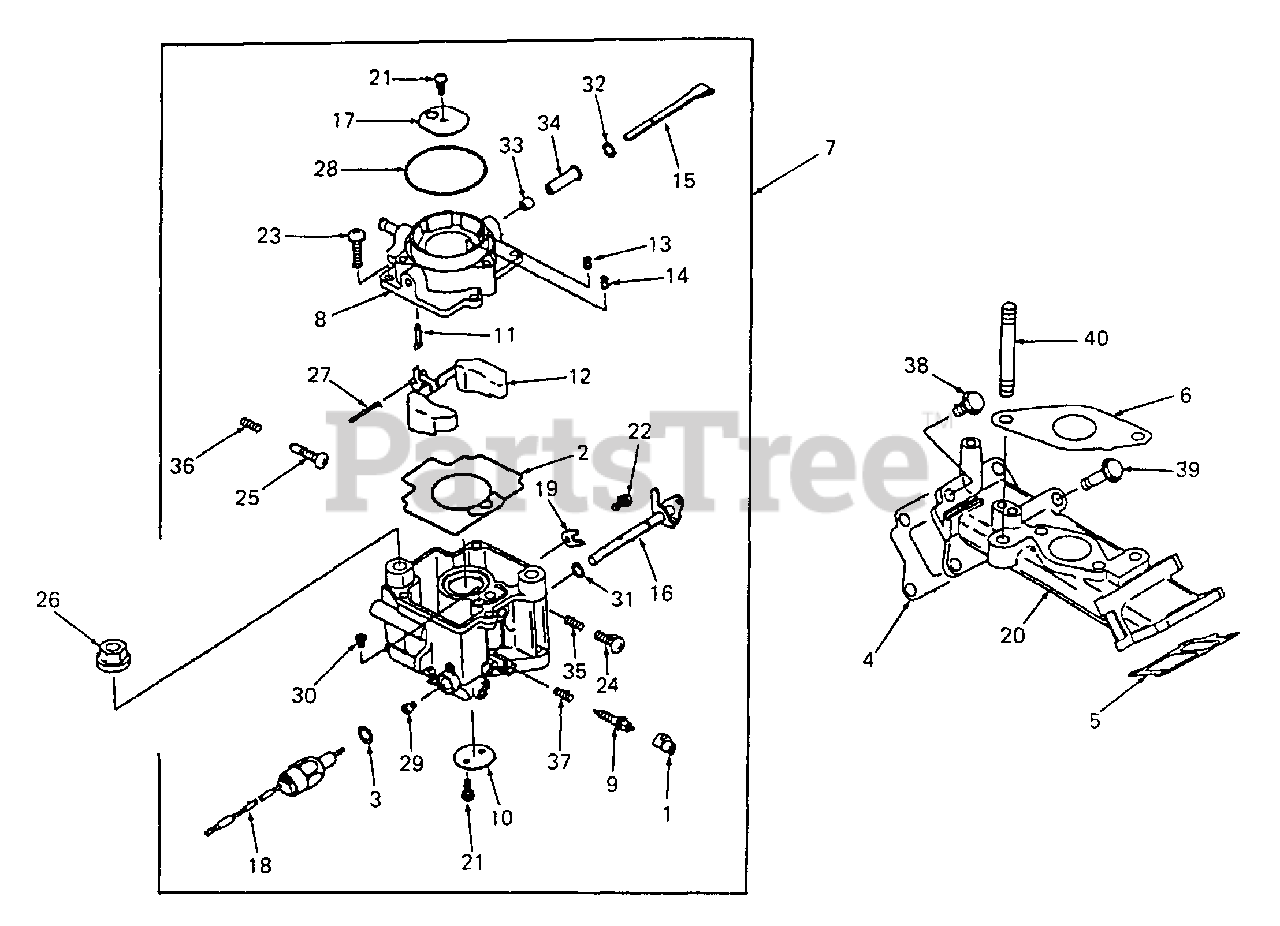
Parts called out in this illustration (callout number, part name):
4	Gasket, Intake Manifold
5	Gasket, Intake Manifold
6	Gasket, Carburetor
7	Carburetor Assy
9	Screw, Pilot Air
10	Valve, Throttle
13	Jet, Air, #1.8
14	Jet, Air, #0.9
16	Shaft, Throttle
18	Solenoid, Fuel
20	Manifold, Intake
21	Screw, 3 x 5.5
28	O-Ring, 49.4 MM
29	Jet, Main, #112
30	Jet, Pilot, #58
31	Seal, Throttle Shaft
32	Seal, Choke Shaft
38	Bolt, Flanged, 6 x 20
39	Bolt, Flanged, 6 x 45
